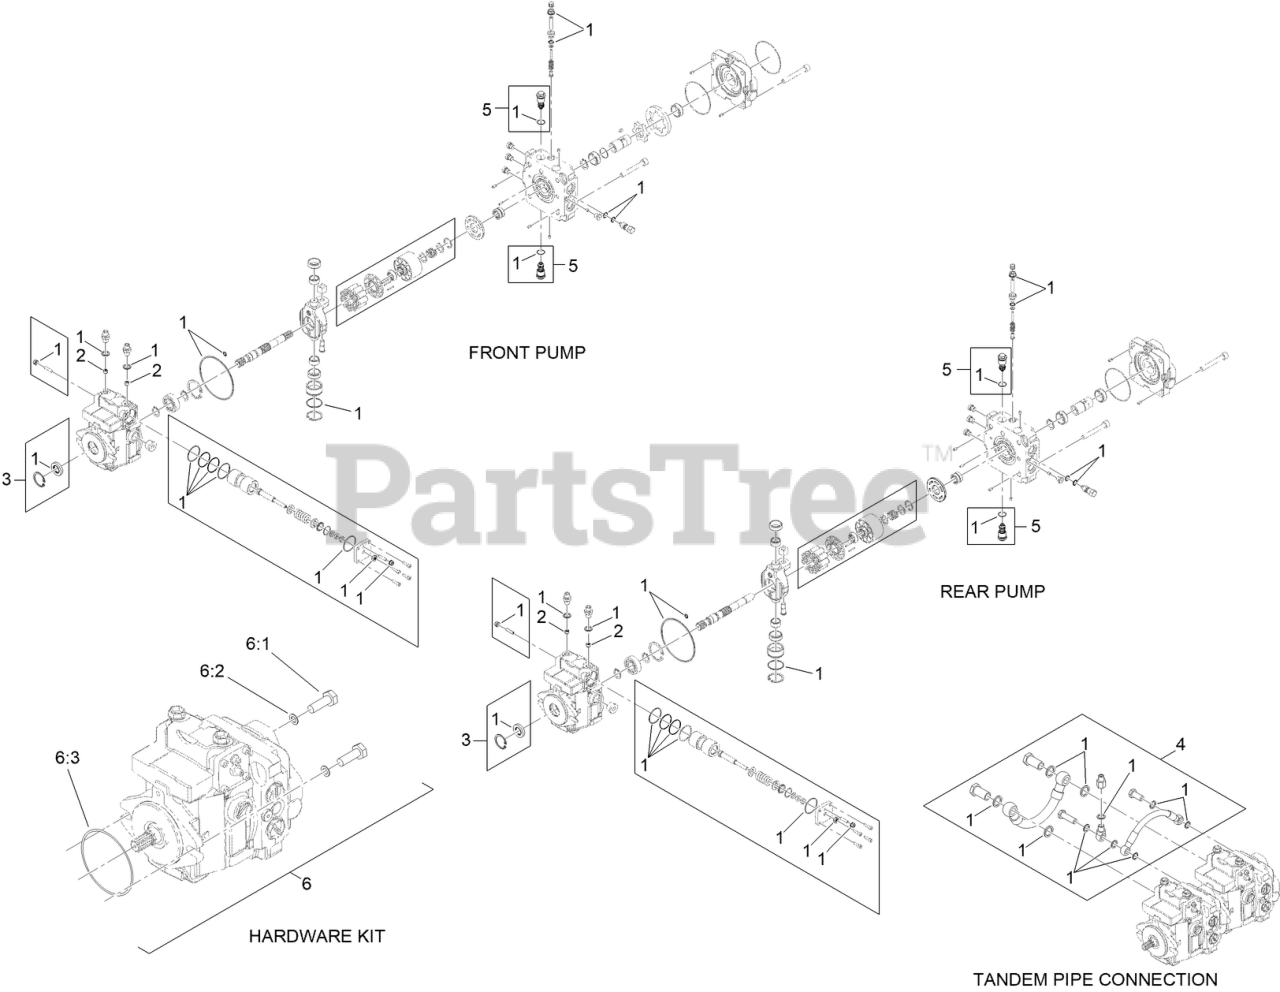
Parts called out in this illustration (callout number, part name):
1	SEAL KIT
2	SPACER-JET
3	SHAFT SEAL KIT
4	TANDEM CONNECTION PIPE KIT
5	VALVE-RELIEF
6	HARDWARE KIT
6:1	BOLT-HEX
6:2	Washer
6:3	O-RING
